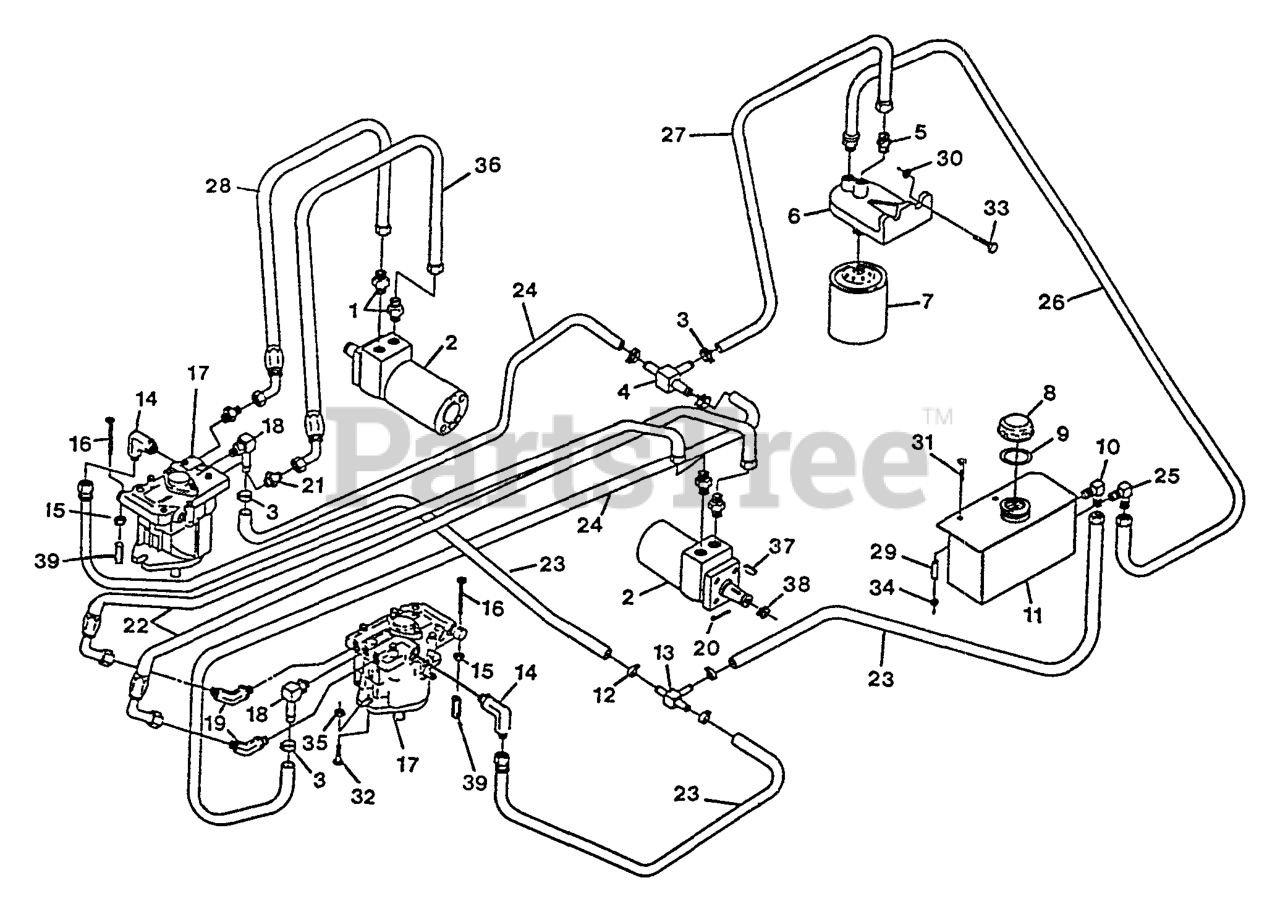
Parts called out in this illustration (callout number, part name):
1	FITTING-STRAIGHT
2	HYD MOTOR ASM
3	CLAMP-HOSE
4	FITTING-TEE, HOSE
5	FITTING-STRAIGHT
9	GASKET-CAP, TANK
10	FITTING-ELBOW
12	CLAMP-HOSE
13	FITTING-TEE, HOSE
14	FITTING-90 DEG
18	FITTING
19	FITTING-HYD, 45 DEG
20	PIN-COTTER
21	FITTING-STRAIGHT
22	HOSE-PRESSURE, HIGH
23	ASM,HOSE CASE DRAIN
25	FITTING-ELBOW
26	ASM,HOSE LO PRESSURE
27	ASM,HOSE CHARGE LINE
37	KEY-WOODRUFF
39	GRIP-VALVE, DUMP
